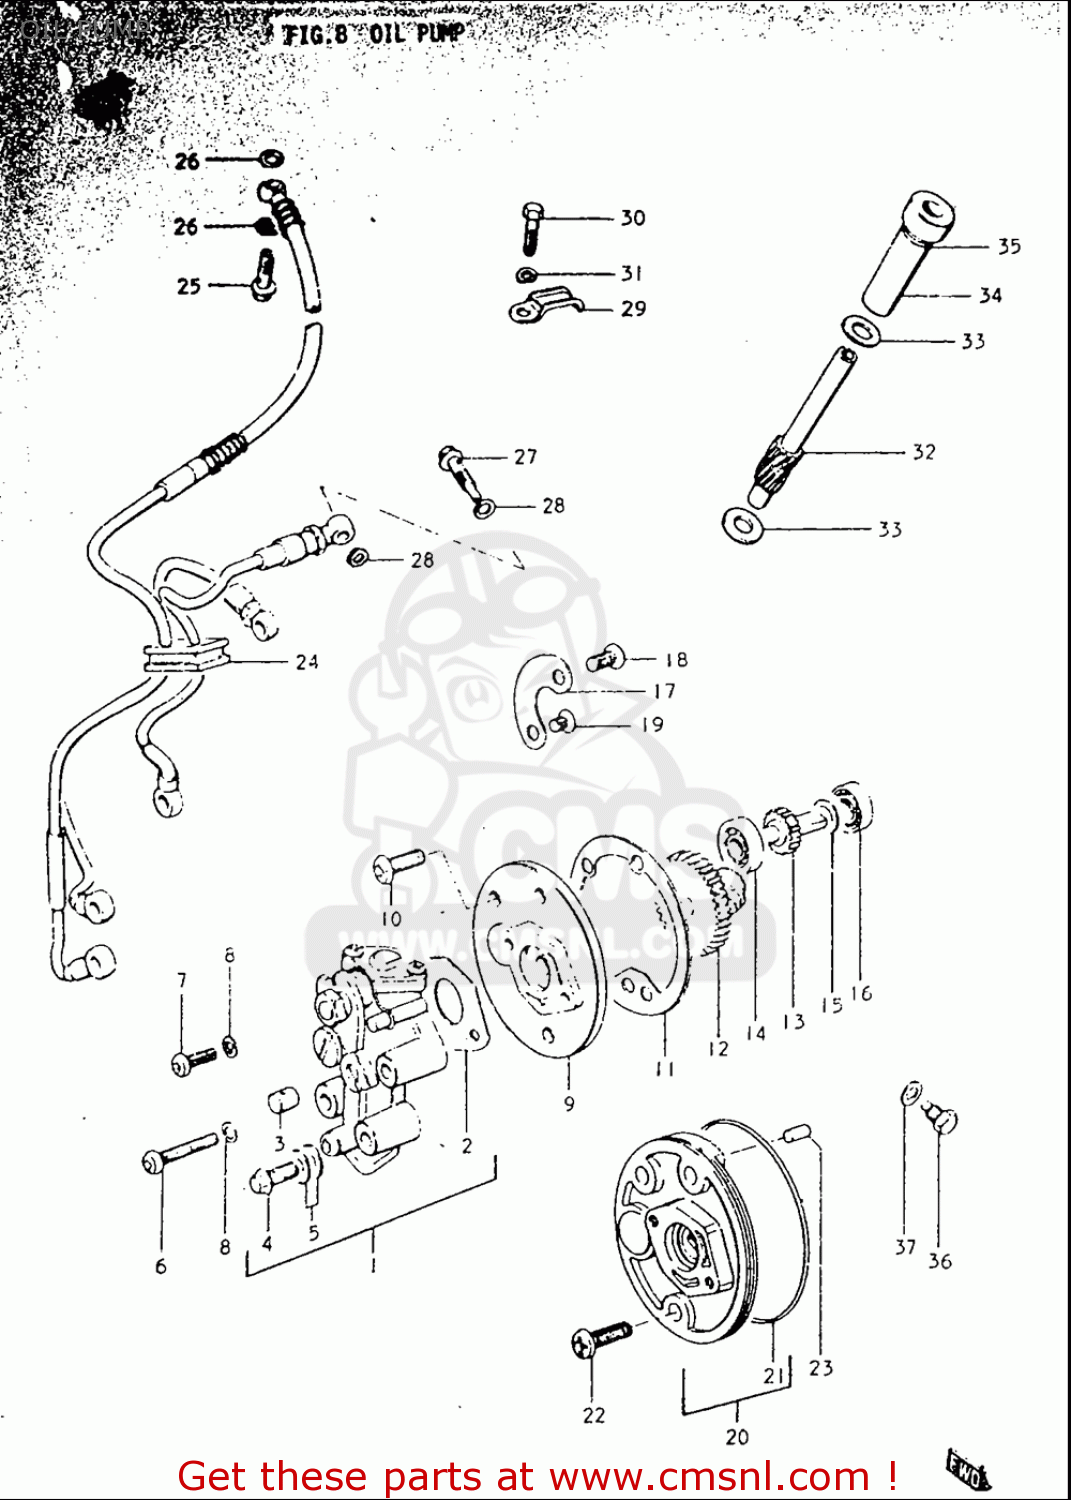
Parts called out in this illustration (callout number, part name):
2	GASKET,OIL PUMP (NAS)
3	TERMINAL,CABLE
4	UNION
5	GASKET(6.2X11X1).2 (NAS)
6	SCREW(5X27)
7	SCREW
8	WASHER,LOCK
15	WASHER(8X13.7X1)
16	BEARING
19	SCREW
21	O-RING (D:2.5 ID:68.5)
25	UNION
26	GASKET(6.2X11X1).2 (NAS)
27	UNION
31	WASHER,LOCK
33	WASHER(8X13.7X1)
35	O RING(D:1.3,ID:9.6)
36	BOLT
37	GASKET(6.2X11X1) (NAS)
